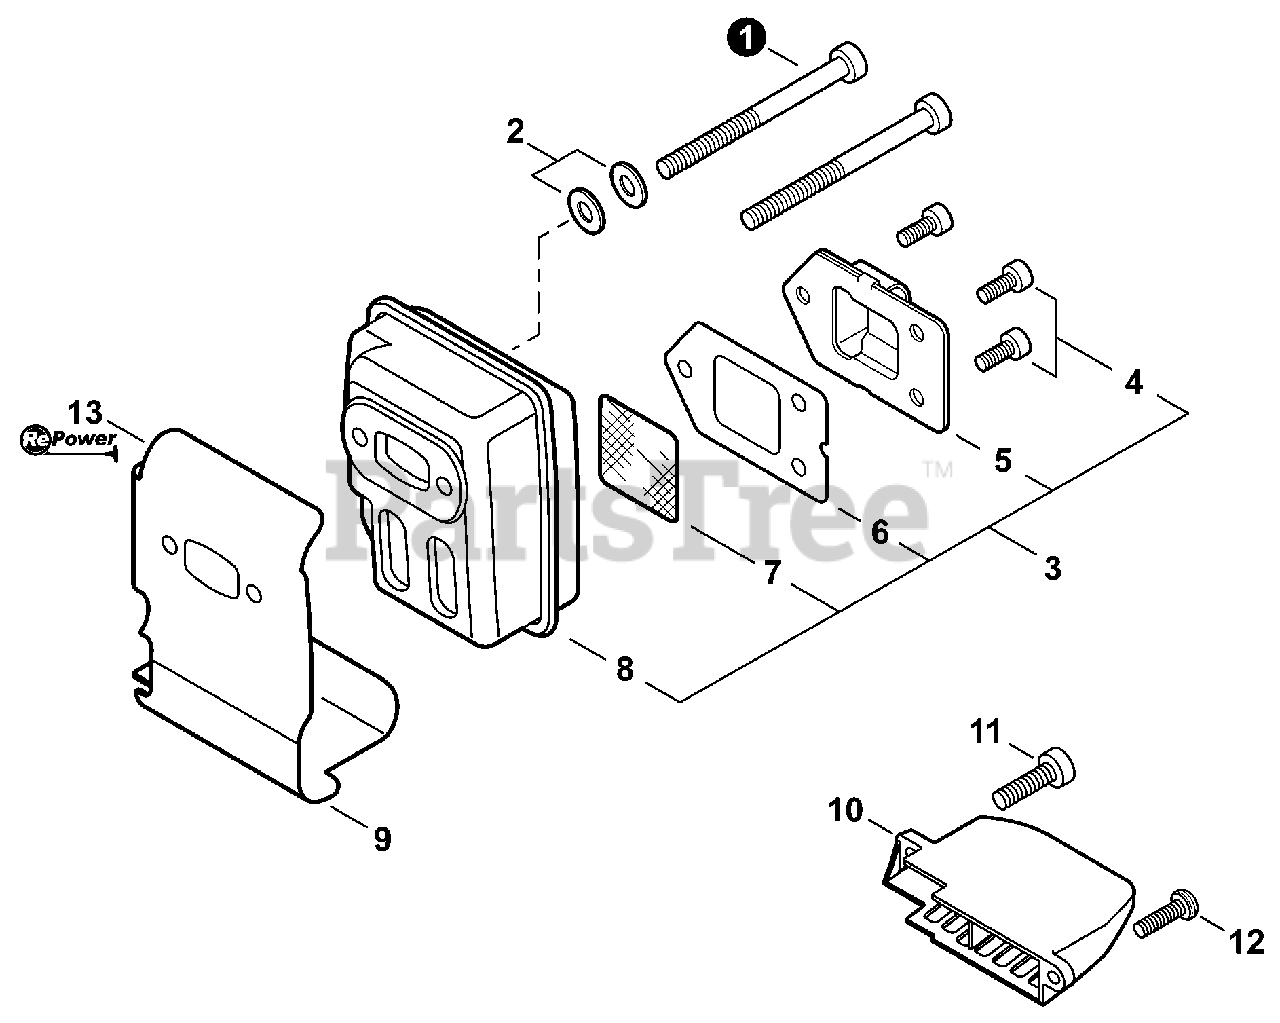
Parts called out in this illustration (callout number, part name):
1	BOLT, TORX 5×55
2	WASHER, FLAT 5.5×10×0.8
3	MUFFLER ASSY
4	BOLT, TORX 4×8
5	GUIDE, EXHAUST
6	GASKET, EXHAUST
7	SCREEN, SPARK ARRESTER
9	GASKET, EXHAUST
10	COVER, MUFFLER
11	BOLT, TORX 5×16
12	BOLT, TORX 5×16
13	GASKET KIT
